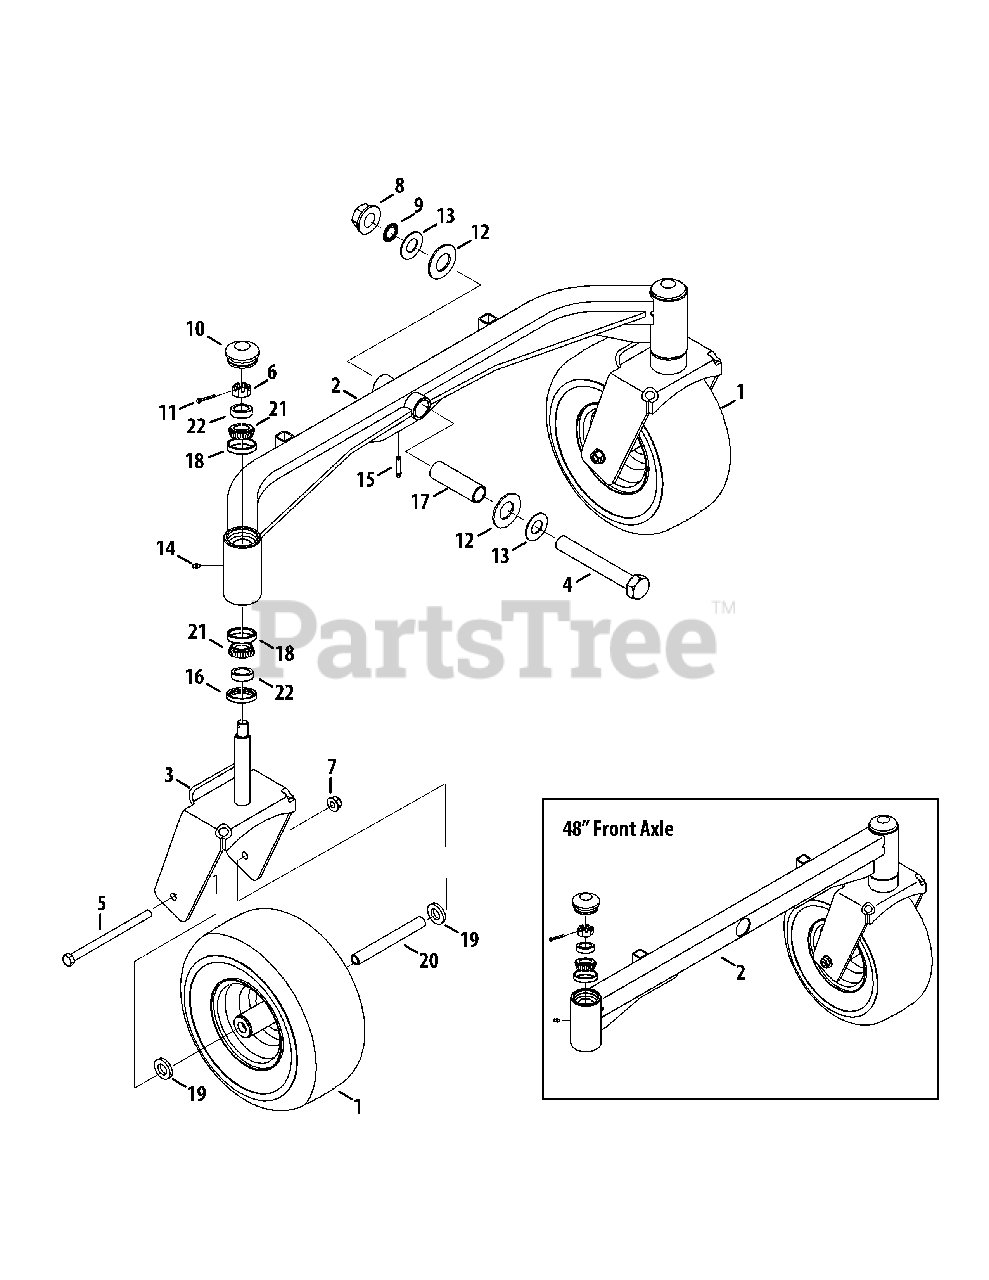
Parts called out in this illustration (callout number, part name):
1	Wheel Assembly, 13 x 6.50-6
2	Front Axle (54" & 60")
3	Yoke, Caster Wheel
4	Hex Cap Screw, 1-14 x 7.0
5	Hex Cap Screw, 1/2-13 x 7.75
6	Nut, 3/4-16, Slotted
7	Nut, 1/2-13, Flangelock
8	Nut, 1.0-14, Flangelock
9	Retainer Ring
10	Axle Grease Cap
11	Cotter Pin, 5/32 x 1.25
12	Bell Washer, 1.25 x 2.50 x .180
13	Washer, 1.00 x 2.00 x .075
14	Grease Fitting, 1/4-28
15	Grease Fitting, 1 39/64
17	Spacer, 1.005 x 1.247 x 4.1
18	Cup Bearing
19	Spacer, .812 ID x .218 LG
20	Spacer, .515 x .749 x 6.313
21	Cone Bearing
22	Spacer, 1.00 x 1.50 x .437
